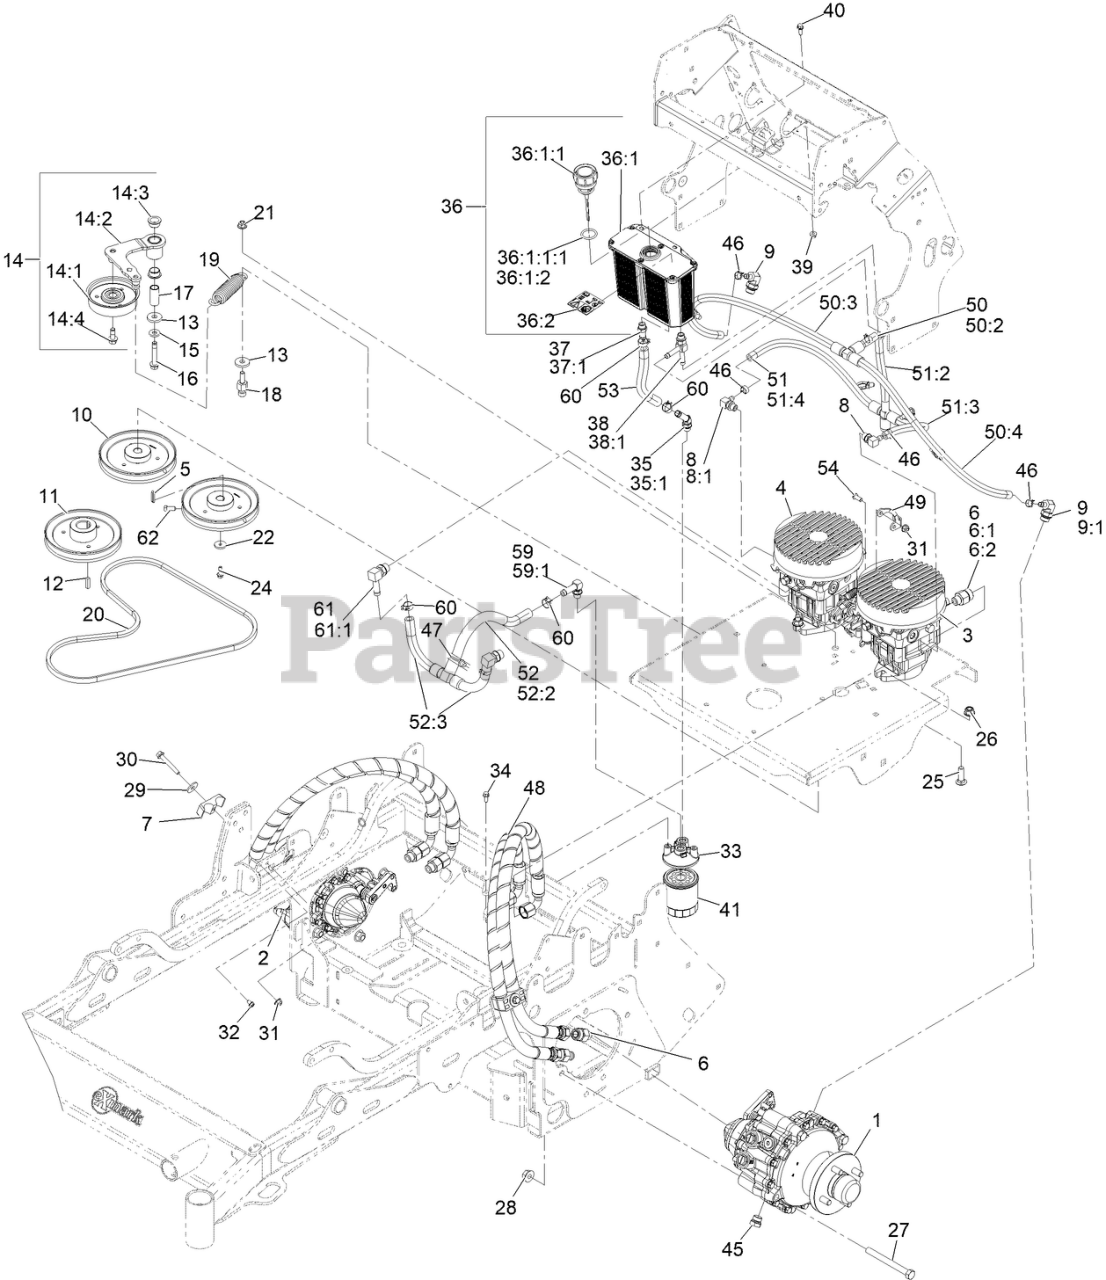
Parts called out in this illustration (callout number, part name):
1	MOTOR-HYD, LH
2	MOTOR-HYD, RH
3	PUMP,16CC LT
4	PUMP,16CC RT
5	KEY, 5MM X 5MM X 29MM
6	FITTING-STRAIGHT
6:1	O-RING
7	CLAMP-TUBE
8	FITTING-90 DEG
8:1	O-RING
9	FITTING-90
9:1	O-RING
10	SHEAVE-PUMP A-SEC 6.31
11	SHEAVE-ENGINE A-SEC 6.31
14	ASM-PUMP IDLER
14:1	PULLEY-IDLER 4.15 FLAT SINGLE FLNG
14:2	ASM-PUMP IDLER ARM
14:3	BUSHING-FLANGE
14:4	SCREW-HFH
15	WASHER-BELLEVILLE
16	SCREW-HHF
17	PIVOT, IDLER
18	PIN-SPRING, ANCHOR
19	SPRING, EXTENSION
20	BELT- COG A 60.0
21	NUT-HF, NI
22	WASHER-1.00 OD X .25 ID
24	SCREW-HHF
25	BOLT-CARR
26	NUT-HF, NI
27	SCREW-HH
28	NUT-HHF
30	CLAMP-TUBE
31	NUT-HF, NI
33	HEAD-FILTER
34	SCREW-HHF
35	FITTING-45
35:1	O-RING
36	Reservoir ASM W/Decal
36:1	Reservoir-HYD
36:1:1	RESERVOIR CAP ASM
36:2	DECAL-HYD FLUID WARN
37	ADAPTER-STRAIGHT
37:1	O-RING
38	ADAPTER-RUN, TEE
38:1	O-RING
39	NUT-HHF
40	SCREW-HHF
41	FILTER-25 MICRON, BI-DIRECTIONAL
45	PLUG-MAGNETIC
46	CLAMP-HOSE
47	CLIP-TIE
48	HOSE ASM-HYD HP
49	BRACKET-PUMP CONTROL
50	ASM-HYDRAULIC LO-PRES
50:2	HOSE-HYDRAULIC LO-PRES
50:3	HOSE-HYDRAULIC LO-PRES
50:4	HOSE-HYDRAULIC LO-PRES
51	ASM-HYDRAULIC LO-PRES
51:2	HOSE-HYDRAULIC LO-PRES
51:3	HOSE-HYDRAULIC LO-PRES
51:4	HOSE- HYDRAULIC LO-PRES
52	ASM-HYDRAULIC LO-PRES
52:2	HOSE-HYDRAULIC LO-PRES
52:3	HOSE-HYDRAULIC LO-PRES
53	HOSE-HYDRAULIC LO-PRES
54	SCREW-HSBH
59	FITTING-ELBOW, 90
59:1	O-RING
60	CLAMP-HOSE
61	FITTING-ELBOW, 90
61:1	O-RING
62	SCREW-SET, SQH
